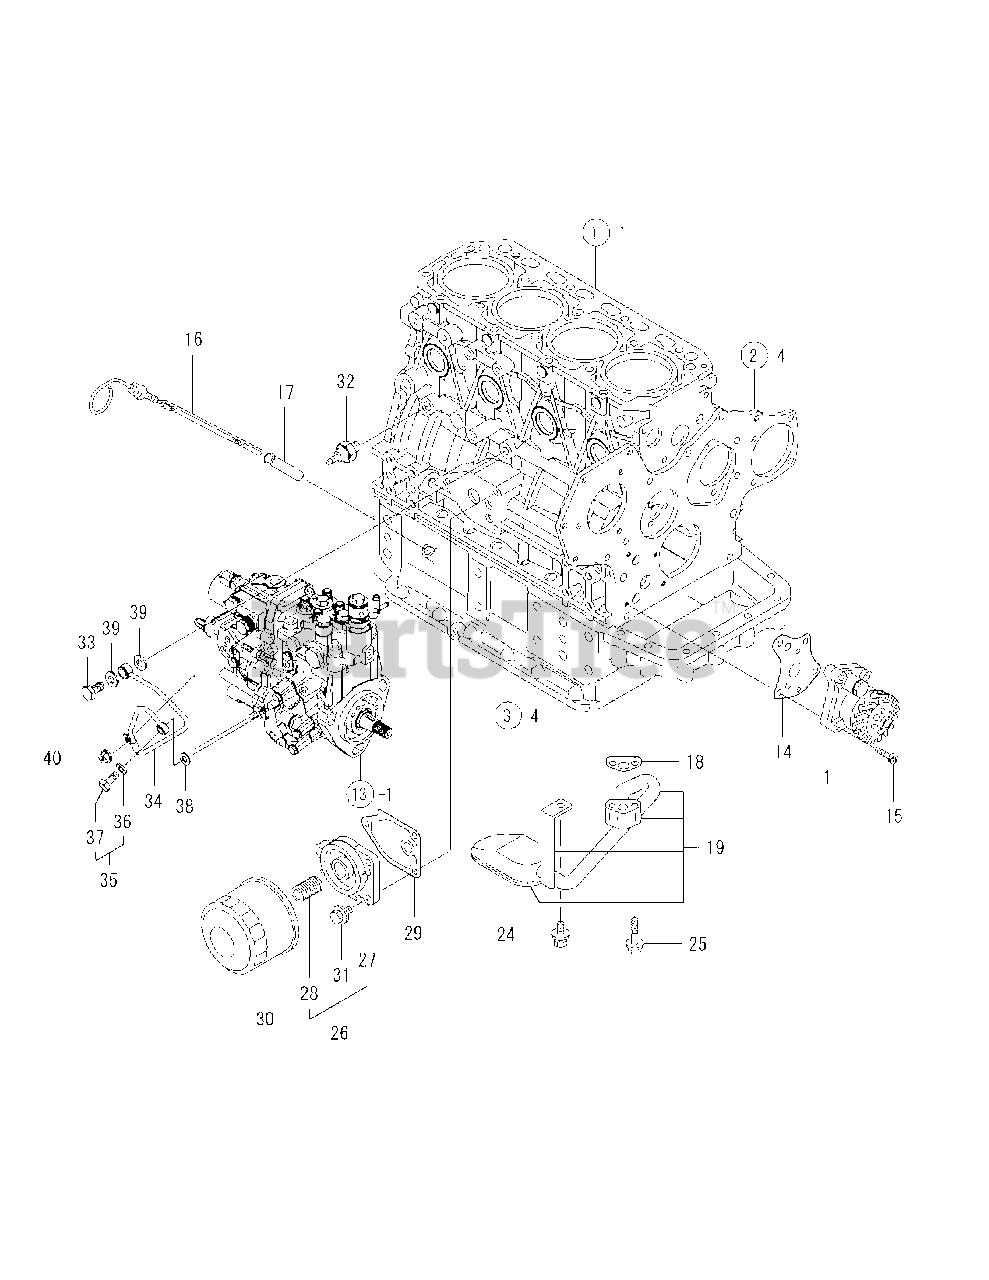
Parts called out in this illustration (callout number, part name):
1	PUMP ASSY, LUB.OIL
16	DIPSTICK, LUB.OIL
17	GUIDE, DIPSTICK
19	PIPE ASSY, OIL INLET
25	BOLT M 8X 35 PLATED
26	BRACKET ASSY, FILTER
27	BRACKET, FILTER
29	GASKET, (NON-ASB.)
31	BOLT M 8X 20 PLATED
32	SWITCH, OIL PRESSURE
33	BOLT, JOINT M10
34	PIPE ASSY, LUB.OIL
35	BOLT ASSY, JOINT
36	SEAL WASHER 8S
38	SEAL WASHER 8S
